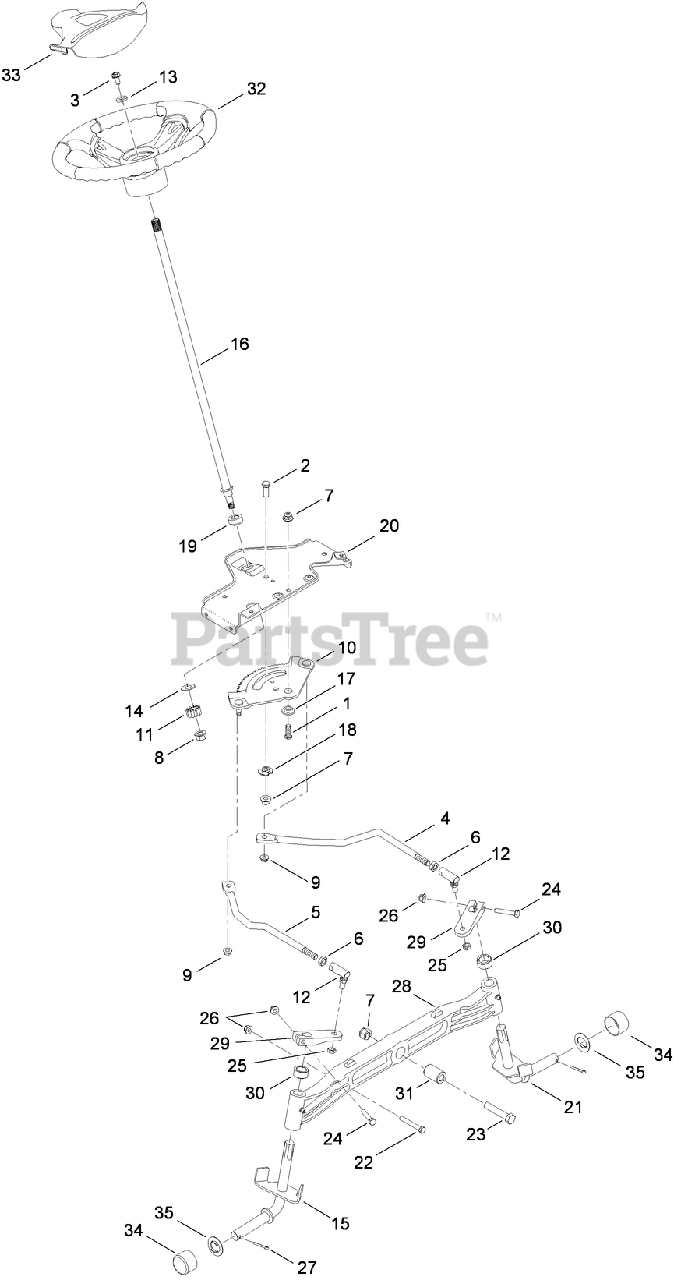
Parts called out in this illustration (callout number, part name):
1	SCREW-HH
2	SCREW-HH
3	SCREW-HH
4	LINK-DRAG, LH
5	LINK-DRAG, RH
6	NUT-JAM
7	NUT-LOCK, FLANGE
8	NUT-LOCK, FLANGE
9	NUT-LOCK, FLANGE
10	GEAR-STEERING
11	GEAR-PINION, STEERING
12	BALL JOINT ASM
13	WASHER-FLAT
14	WASHER-FLAT
15	RH AXLE ASM
16	SHAFT-STEERING
17	SPACER-SHOULDER
18	SPACER
19	BEARING-FLANGE, HEX
20	BRACKET-SUPPORT, STEERING
21	LH AXLE ASM
22	SCREW-HH
23	SCREW-HH
24	BOLT-HH
25	NUT-HEX, LOCK
26	NUT-LOCK, FLANGE
27	PIN-COTTER
28	AXLE-CAST
29	BLOCK-STEERING
30	SPACER
31	SPACER
32	WHEEL-STEERING, SOFTGRIP
33	COVER-WHEEL, STEERING
34	CAP-BUMPER
35	WASHER-FLAT
